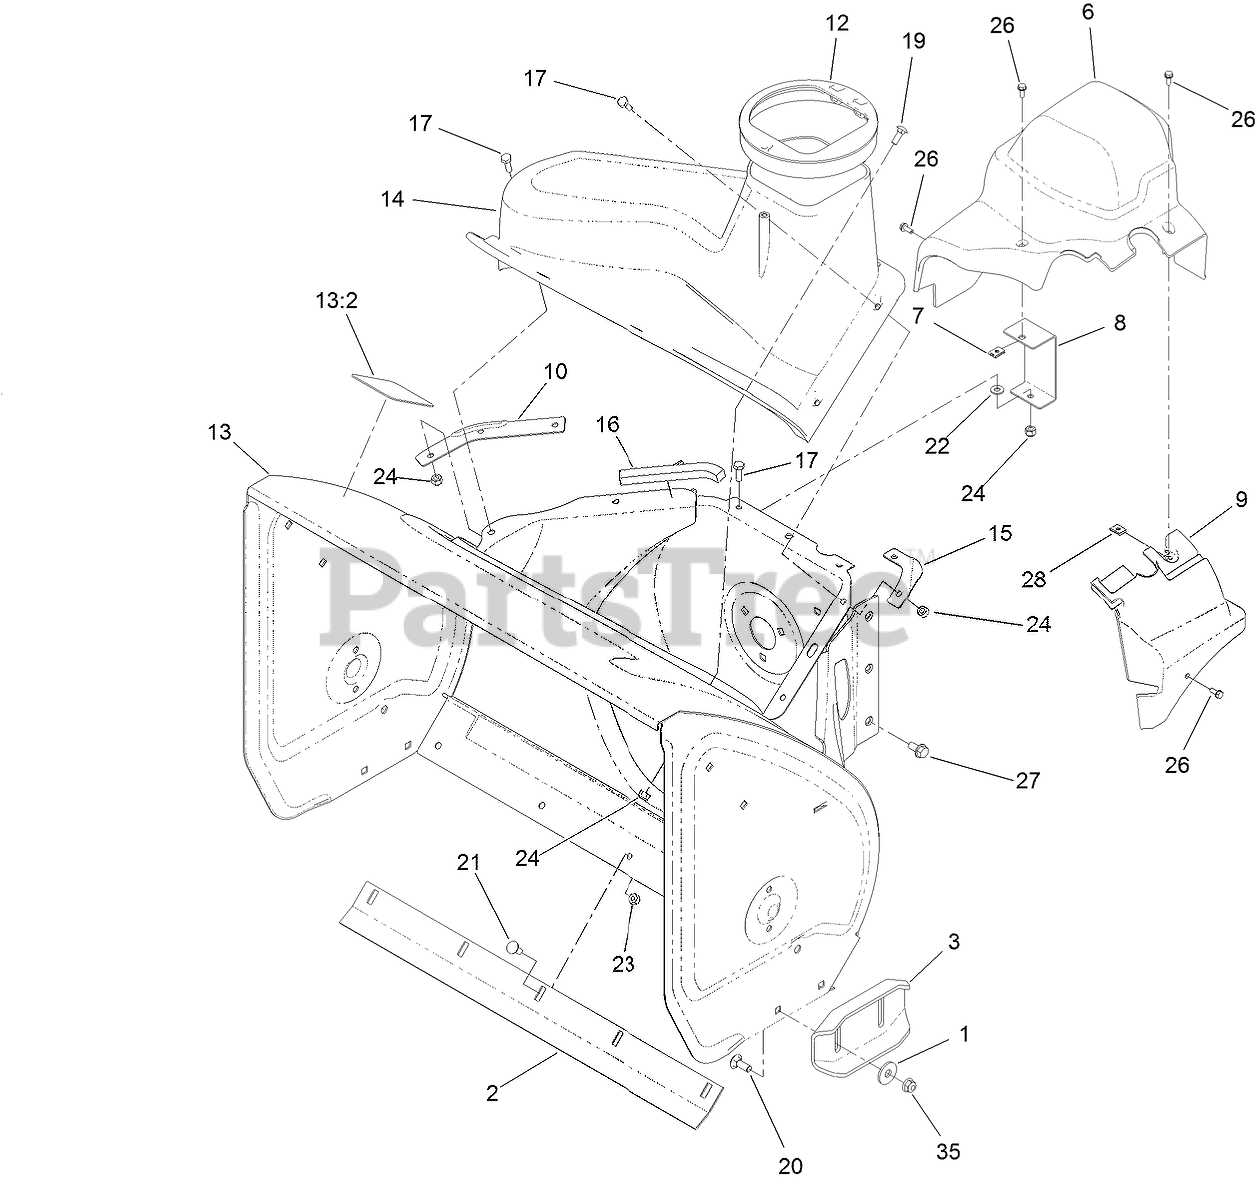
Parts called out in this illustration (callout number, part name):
1	WASHER-FLAT
2	SCRAPER-FIXED
6	COVER-BELT
7	NUT-SPEED
8	BRACKET-COVER, CLIP NUT
9	COVER-EXTENSION, BELT
10	SEAL-FLANGE, COVER
12	GUIDE-CHUTE
13	HOUSING-AUGER, 28 INCH
13:2	DECAL-DANGER, AUGER
16	SEAL-HOUSING
17	SCREW-HH
19	BOLT-CARR
20	BOLT-CARR
21	BOLT-CARR
22	WASHER-FLAT
23	NUT-HEX
24	NUT-HEX
26	SCREW-HWH
27	SCREW-HWHTF
28	NUT-SPEED
35	NUT-HF
